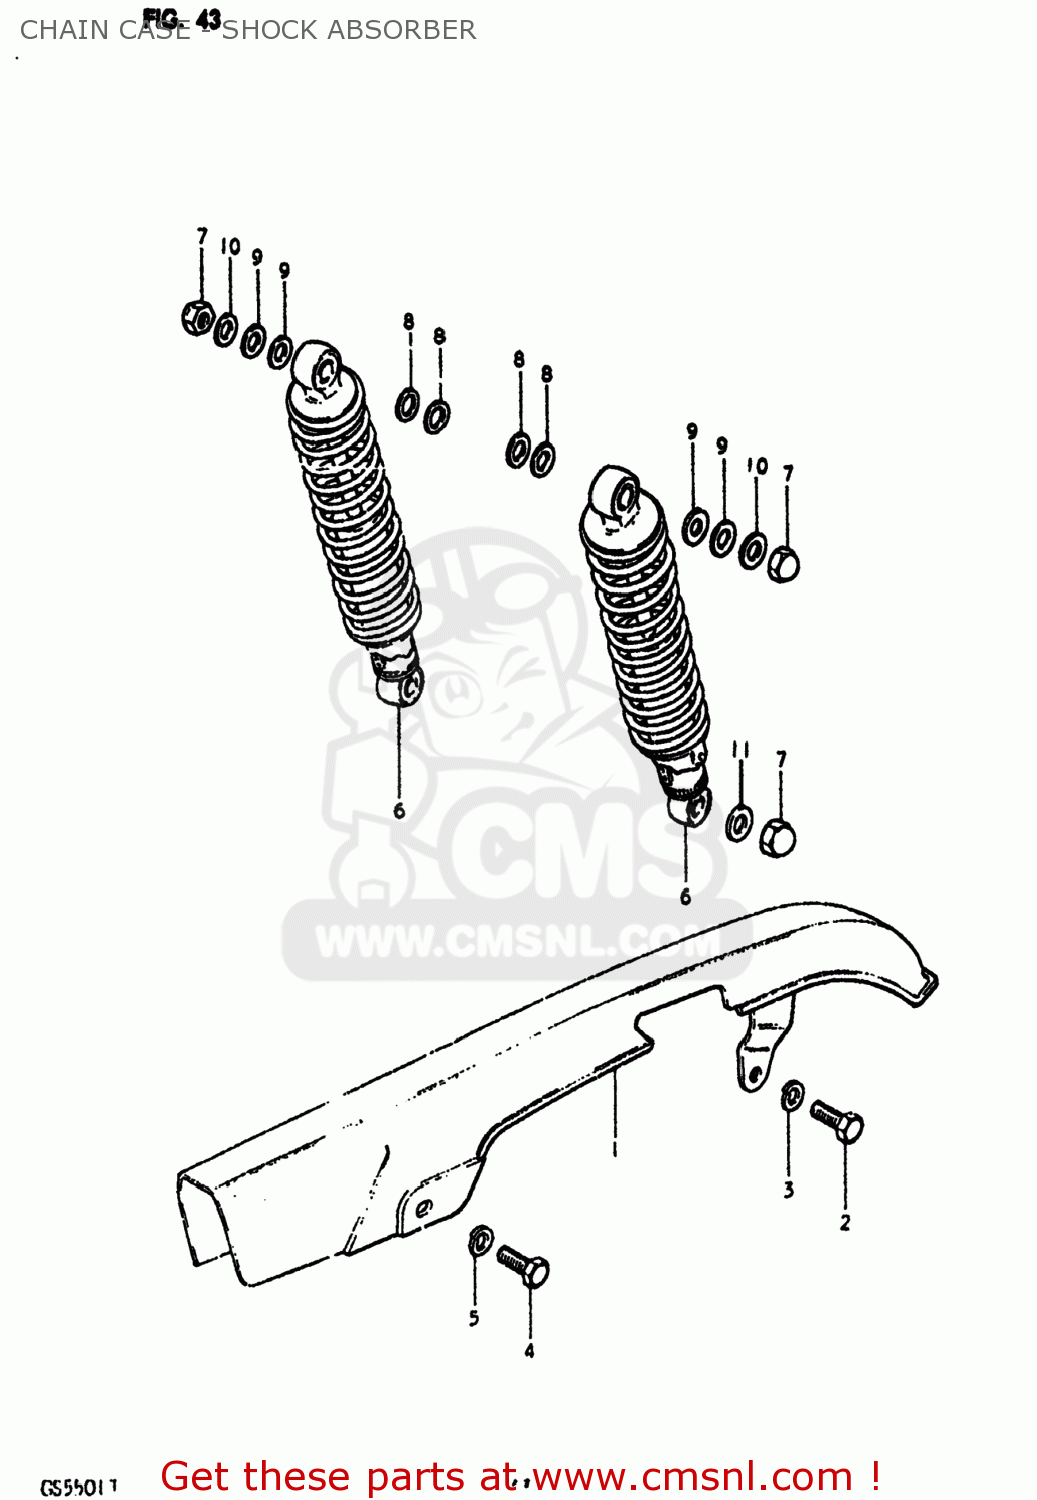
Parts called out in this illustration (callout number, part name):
1	CASE,CHAIN
2	BOLT
3	LOCK WASHER
4	BOLT
5	LOCK WASHER
6	ABSORBER ASSEMBLY,REAR SHOCK
7	NUT, LOWER LH
8	WASHER
9	WASHER
10	WASHER(10.5X24X3.2)
11	WASHER
